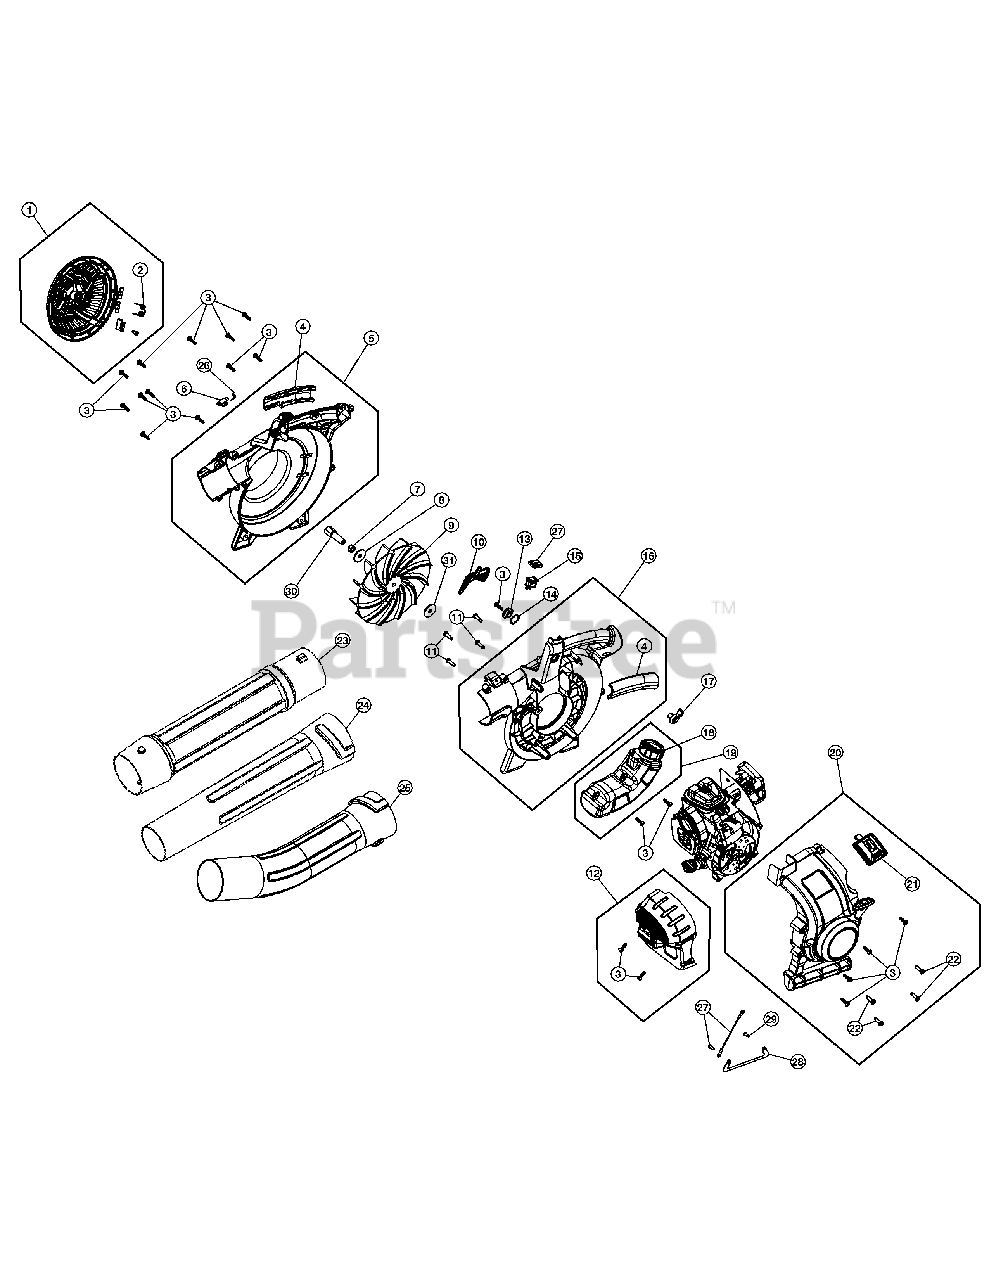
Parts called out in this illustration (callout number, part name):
1	Intake Cover Assembly
2	Spring
4	Handle Grips
5	Impeller Housing (Incl. 4)
6	Latch Tube
8	Washer
9	Impeller
10	Throttle Trigger
11	Screw
12	Muffler Cover (Incl. 3)
13	Inner Trigger Lock
14	Wavey Washer
16	Impeller Housing (Incl. 4)
17	Outer Trigger Lock
18	Fuel Cap
19	Fuel Tank Assembly (Incl. 18)
20	Engine Cover Assembly (Incl. 3, 21 & 22)
21	Spark Plug Cover
23	Upper Tube
24	Lower Tube
25	Flare Tube
26	Latch Spring
27	Wire Ground
28	Strap Ground
29	Screw
30	Adapter
31	Spacer
